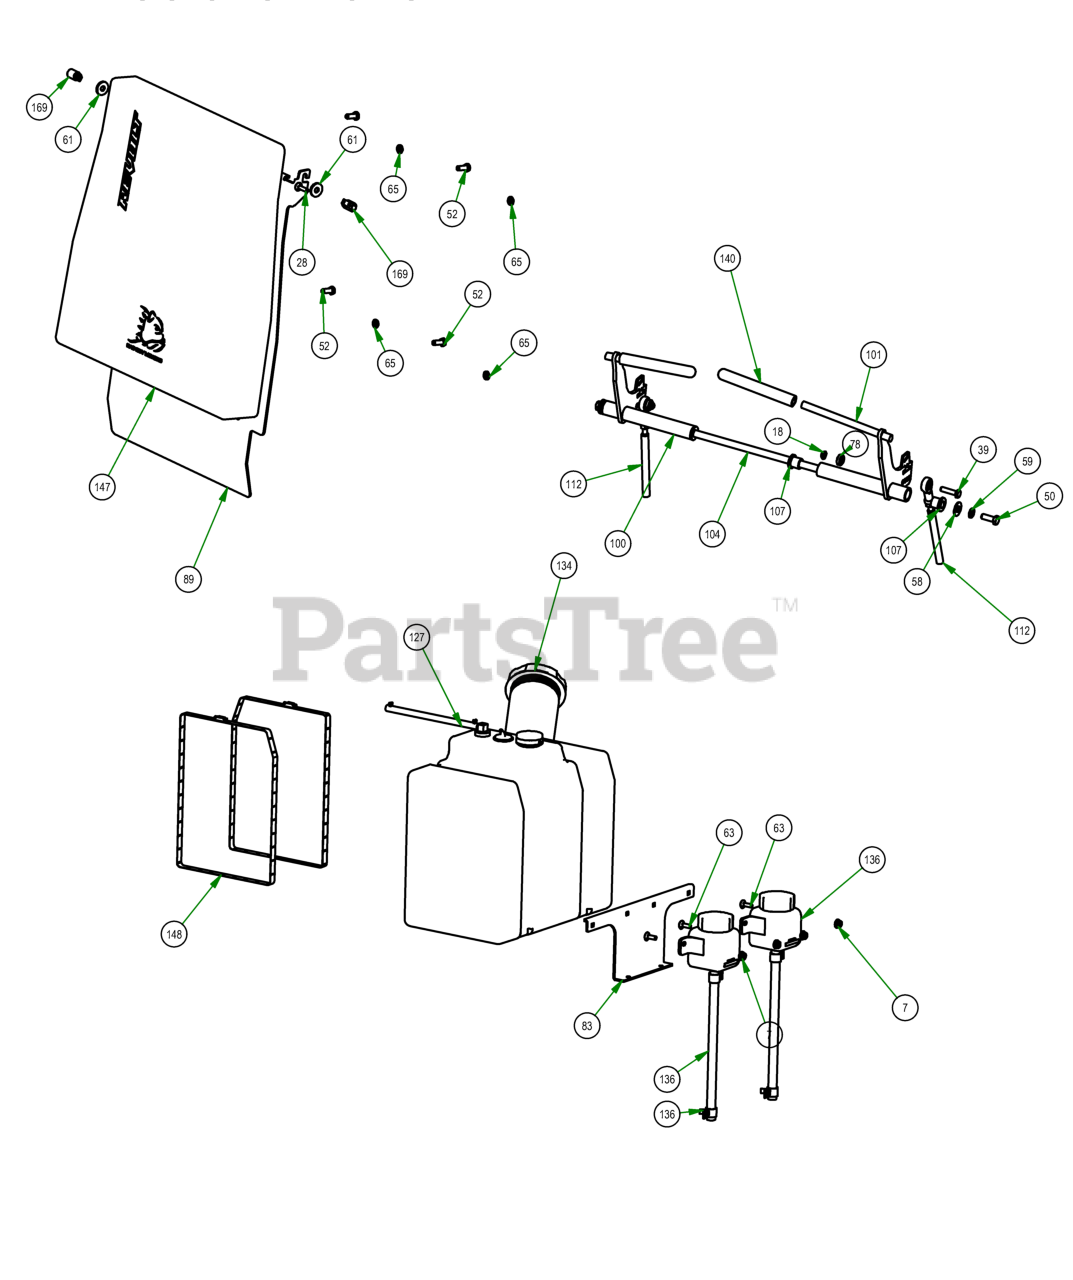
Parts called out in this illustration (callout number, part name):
4	8-32 HEX M/S NUT ZINC
7	1/4-20 NYL INSERT FLANGE LOCKNUT ZINC
8	10-24 NYLON INSERT LOCKNUT ZINC
10	3/8-16 Nylon Insert Flange Locknut
12	3/8-24 HEX NUT ZINC YELLOW
13	5/16-18 NYLON INSERT FLANGE LOCKNUT ZINC
16	5/16-18 HEX SERRATED FLANGE NUT HARD/ZINC
18	5/16-18 Nylock Insert Jam Locknut
20	5/8 Round Insert
26	M6-1.0 X 16MM Hex Bolt
28	1/4-20 X 1 CARRIAGE BOLT (GR.5) ZINC
30	5/16-18 X 6 CARRIAGE BOLT (GR.5) ZINC
36	12-24 X 1/2 HEX WASHER UNLSOT F TCS ZINC
39	5/16-18 X 1-1/4 HEX C/S (GR.5) ZC
43	5/16-18 X 1-1/2 CARRIAGE BOLT ZINC
45	3/8'' x 1 1/4'' Carriage Bolt
47	10-24 X 5/8 BUTTON SOCKET CAP SCREW 18-8 STAINLESS STEEL
50	3/8-16 X 1 GR 5 Hex Bolts Zinc
52	5/16-18 X 3/4 HEX CAP SCREW (GR.5) ZINC
53	5/16-18 X 1 CARRIAGE BOLT (GR.8) ZINC
55	.390 ID X .750 OD X .062 THK FLAT WASHER NYLON
57	.390 ID X 1.12 OD X .125 THK FLAT WASHER NYLON
58	3/8 FLAT WASHER USS (1" OD) ZINC
59	3/8 SPLIT LOCKWASHER ZINC
61	.360 ID X .983 OD X .120 THICK FLAT WASHER NYLON
63	1/4-20 X 3/4 CARRIAGE BOLT (GR.5) ZINC
65	5/16 SPLIT LOCKWASHER ZINC
73	Expandable Locking Grommets
78	ACS Spacer 3/4x3/8x1/4
83	2020 36" Hydrotank Carrier Plate - Raw 2020 36" Stand On
88	2023 Stand on Battery Hold Down
89	2023 36-SD Stand on Pad Plate
96	2023 Floor Board Rubber Bumper
99	36" Front Control Arm Stop Weldment - Raw 2020 36" Stand On
100	2023 36-SD Stand On Drive Arm Actuator weldment_left
101	2023 36-SD Stand On Drive Arm Actuator weldment_right
102	2023 36''/SD Control Arm Stop Weldment_Rear
104	2020 36 Stand On Drive Arm Pivot Bar
107	Nylon 6 6 Sleeve Washer
111	Brake Spring
112	2019 Revolt Push Rod Assembly
113	2023 36-SD Stand On Console Bracket Weldment
118	Ignition Key
124	1/4" Vinyl Tubing, 46" Long
125	3/16" Vinyl Tubing, 55" Long
127	Revolt Fuel Line Assembly
129	Universal Throttle Head - 2012
130	Throttle Knob
131	PTO Switch
133	Brake Cable
135	MZ Kohler EPA Canister Assembly
136	Hydro Tank Assembly
137	Interstate FAYTX14 Battery
138	8507A13 McMaster Carr Plunger
139	2019 Stand On Brake Handle - Raw
140	2019 Stand On Control Grip
142	Rubber Brake Grip-cZT/ZT 2013
146	2019 Stand On Waterbottle Cage
147	SD Seat Pad
149	3/16 Vinyl Clamp
150	3/16" Vinyl Hose Clamp
152	Magnet-Steering Arm-Stand ON
154	Safety Switch
155	Ignition Switch
156	2023 SD Podium Panel Right
157	2023 SD Podium Panel Left
158	36" Podium Front Panel Weldment 2020 Stand On
159	Tachometer
160	Safety Switch Harness
163	36" Control Panel (upper) - Revolt
164	36" Control Panel (lower) - Revolt
169	Adjustable handles ERX.30 B-10-24-C1
